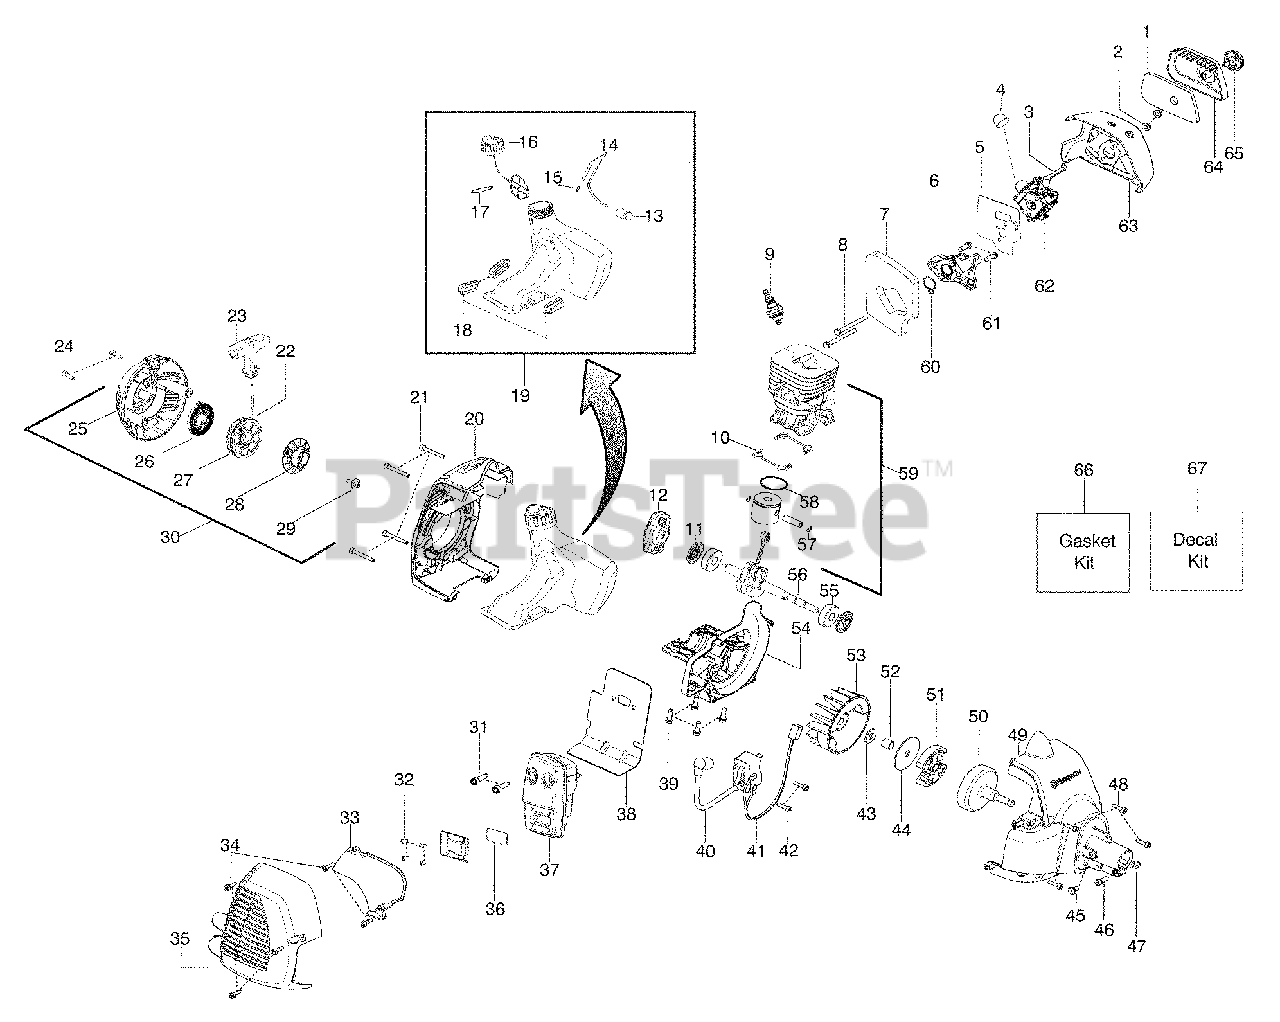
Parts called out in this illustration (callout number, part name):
2	Nut-Carb. Screw
3	Lever - Choke
4	Bulb-Purge
5	Kit-Carb. Gasket
6	Adaptor-Carb.
7	Foam-Gasket
9	Plug-Spark (RCJ-6Y)
10	Seal-Cylinder
11	Seal-Crankshaft
12	Assy-Starter Pawl
13	Assy-Fuel Filter
14	Kit-Fuel Line
15	Fitting-Fuel Line
16	Assy-Cap w/ret.
17	O-ring - Fuel Cap
18	Isolator-Tank
19	Kit-Fuel Tank Assy.
20	Shroud-Rear
22	Kit-Rope
23	Handle-Starter
25	Starter Hsg. w/eyelet
26	Kit-Starter Spring
27	Kit-Starter Pulley
28	Pulley-Driver
30	Assy-Starter Hsg.
31	Bolt-Muffler
32	Screw
33	Shield-Heat
35	Guard-Muffler
36	Kit-Spark Arrestor
37	Assy-Muffler
38	Gasket-Paper Met.
40	Module
41	Assy-Leadwire
44	Washer-Clutch
49	Assy-Fan Housing
50	Assy-Clutch Drum
51	Kit-Clutch Assy.
54	Crankcase-Cast
56	Assy-Crankshaft
57	Retainer-Piston Pin
58	Ring-Piston
59	Kit-Piston/Cyl.
60	Seal-adaptor
62	Kit-Carb.
63	Air box
64	Cover-Air Box
66	Kit-Gasket
